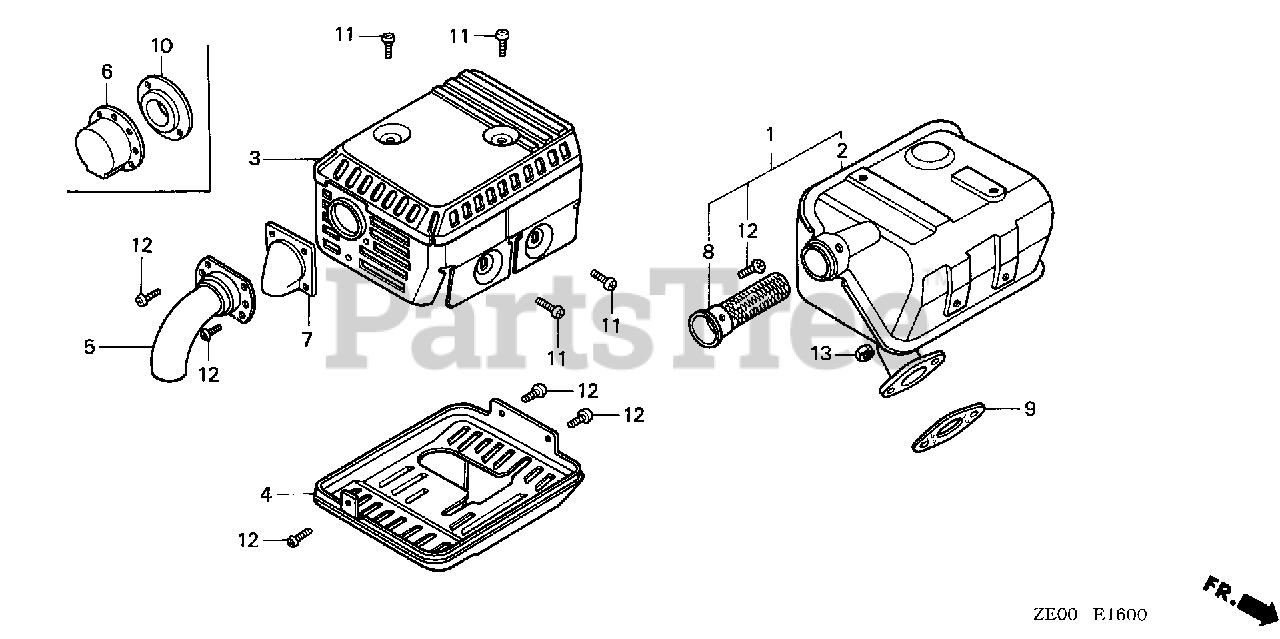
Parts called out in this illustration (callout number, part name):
1	MUFFLER (ARRESTER) (NOT AVAILABLE)
3	PROTECTOR (UPPER)
8	ARRESTER, SPARK
9	GASKET, MUFFLER
10	GUIDE, MUFFLER
11	SCREW, TAPPING (5X8)
12	SCREW, TAPPING (4X6)
13	NUT, HEX. (8MM)
